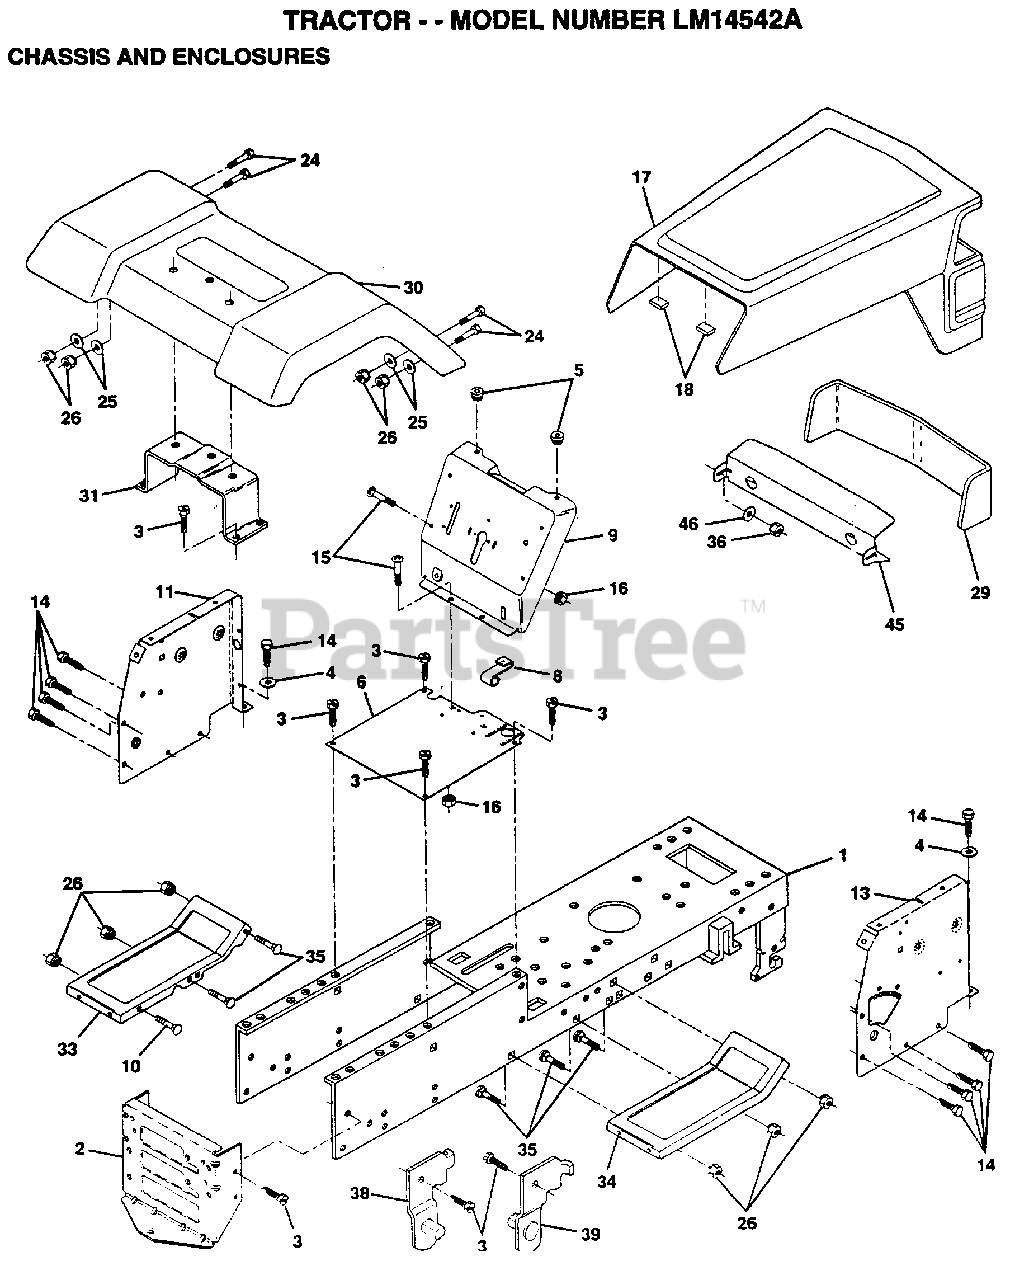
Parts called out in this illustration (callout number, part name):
1	CHASSIS.WLD.11GA
3	SCREW
4	WASHER
8	"CLIP,INSULATOR"
9	DASH.SLKSC.LT.1PC
11	PANEL.DASH.LH.
14	SCREW LT
15	SCREW
17	HOOD/GRILL ASM
24	BOLT
25	WASHER
26	NUT
31	BRKT FENDER
33	FOOTREST.LH.LT/GT
34	FOOTREST.RH.LT/GT
35	BOLT
36	PAL NUT LT
38	BRACKET ASM LH
39	BRACKET ASM RH
46	RETAINER
